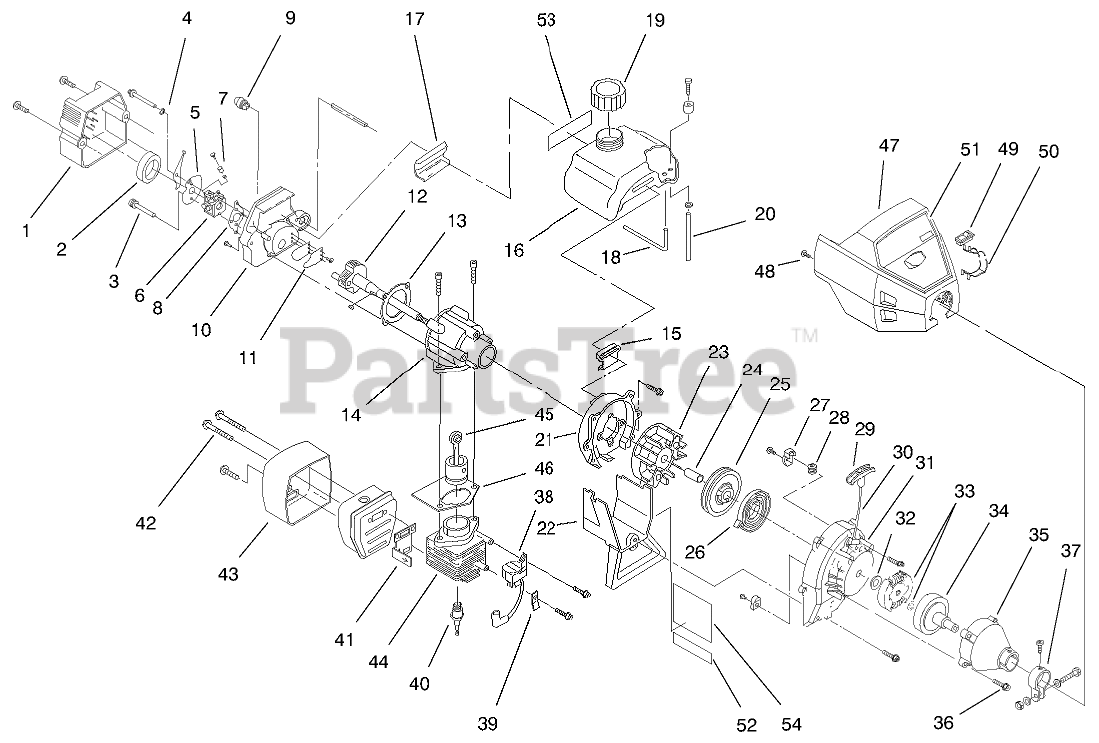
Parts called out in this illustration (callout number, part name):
1	Plate-Logo
2	Plate-Engine Logo
3	NUT-JAM
4	GASKET-AIR CLEANER
5	Air Cleaner Assembly (Incl. Ref. #6, 8 & 9)
6	WASHER-FLAT
7	HEX FL HD M.6X1.0X25MM
8	NUT-HEX
9	AIR CLEANER COVER WA
10	SPIT BACK DEFLECTOR
11	5/16 ID BSHG
12	NUT-LOCK
13	SCREW-HHF
14	FILTER
15	AIR CLEANER COVER
16	AIR CLEANER GUARD
